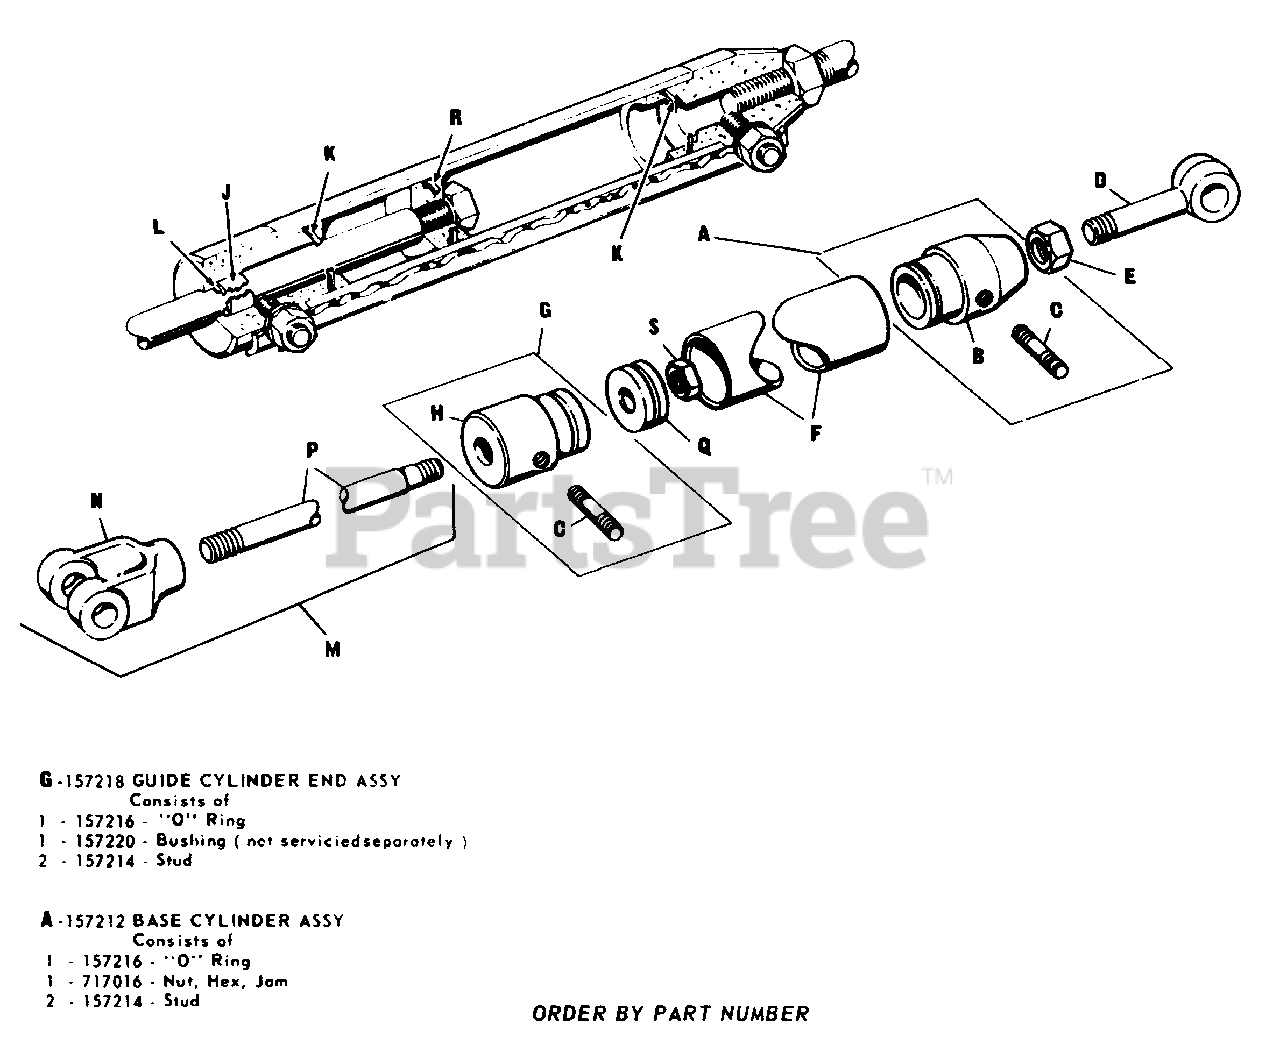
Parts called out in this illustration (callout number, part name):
A	Cylinder Base Sub-Assembly
B	Cylinder Base
C	Stud Bolt 5/16"-18 x 7/8"
E	Jam Hex. Nut 1/2"-20
G	Sub Assembly Guide
H	Cylinder End Guide
M	Yoke & Rod Sub-Assembly
P	Piston Rod
S	Full Hex. Nut
